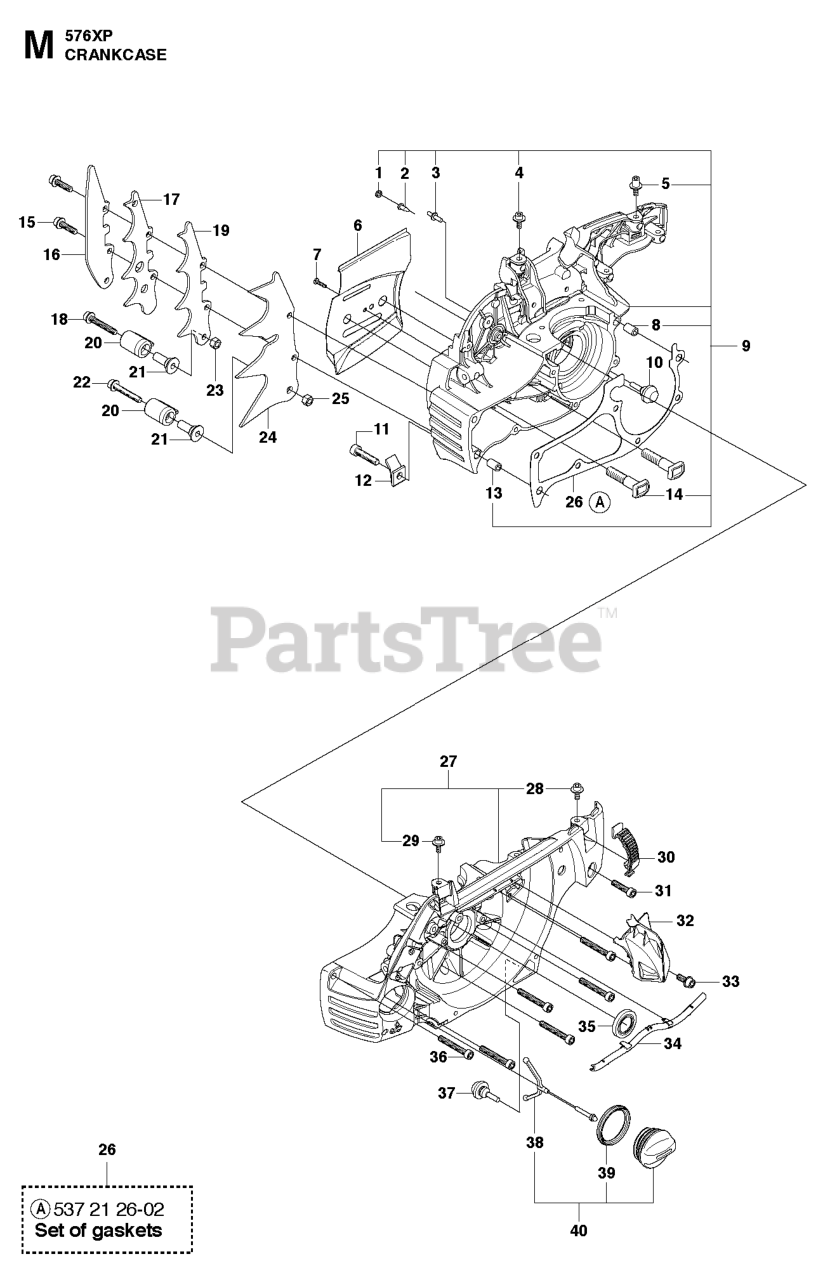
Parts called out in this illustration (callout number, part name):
1	PLUG
2	VALVE-CHECK (DUCKBILL)
4	SCREW IHSCM
5	SCREW IHSCM
8	GUIDE BUSHING
9	CRANKCASE ASSY
12	CHAIN CATCHER
13	GUIDE BUSHING
17	FELLING DOG
18	SCREW IHSCFM
19	FELLING DOG
21	CHAIN CATCHER
22	SCREW IHSCFM
24	FELLING DOG
26	GASKET KIT
27	CRANKCASE ASSY
28	SCREW IHSCM
29	SCREW IHSCM
30	CLIP GRAY
33	SCREW
35	RADIAL SEAL
38	HOLDER
